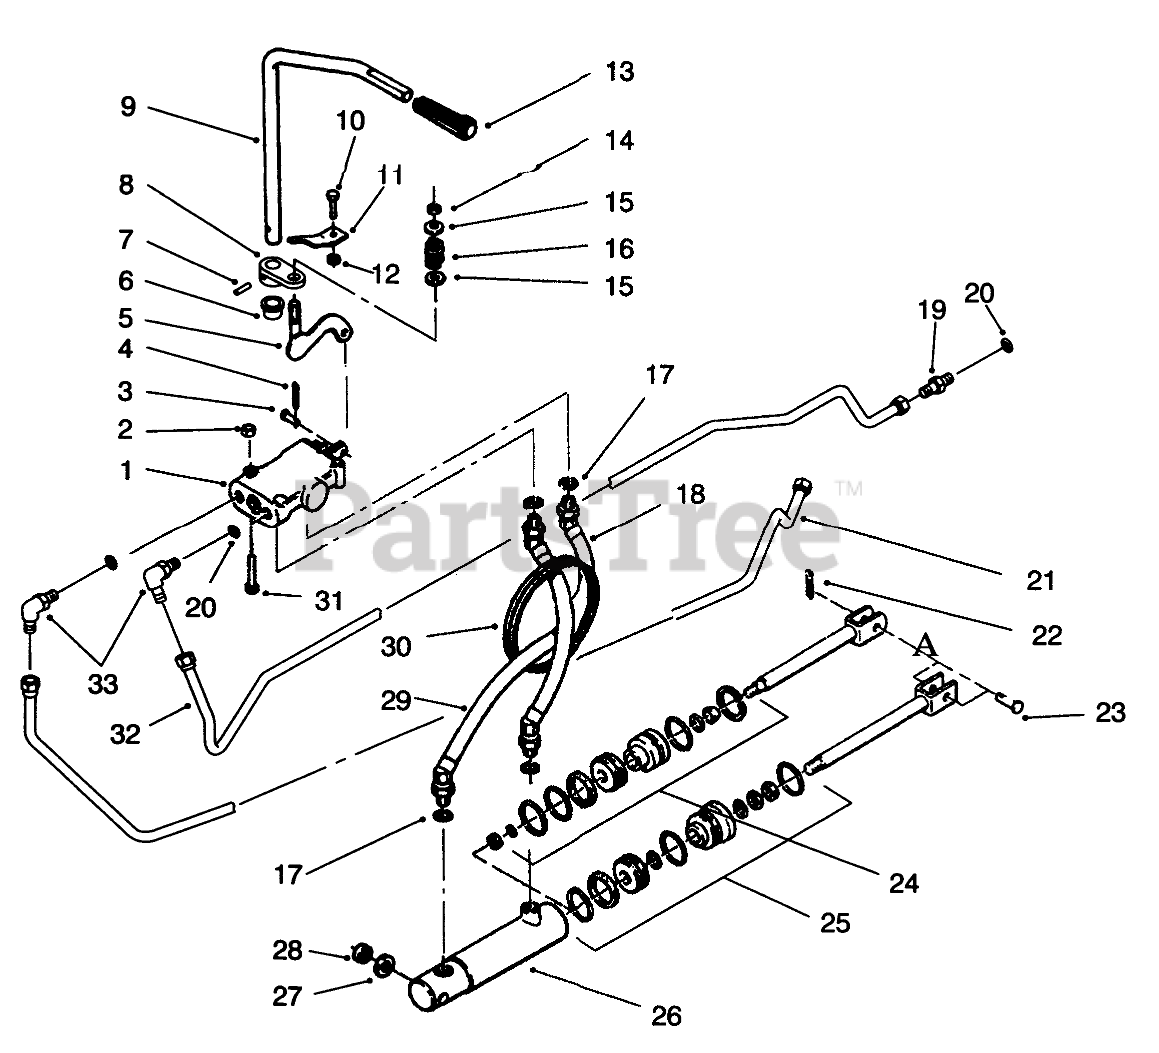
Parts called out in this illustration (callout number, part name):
1	Valve-Hydraulic (Incl. Ref. #3-4)
2	NUT-LOCK, NI
3	PIN-CLEVIS
4	PIN-COTTER
5	WLDMT-LIFT BAR
6	NYLINER BUSHING
7	SPIROL PIN 7/32X7/8
8	ARM-CONTROL
9	ROD-LIFT CONTROL
10	SCREW-HH
11	BRACKET-CONTROL R B
12	NUT-LOCK, NI
13	KNOB-HYDRAULIC LIFT
14	NUT-LOCK, NI
15	WASHER-PLAIN
16	SPRING
17	O RING
18	Hose ASM-Hydraulic
19	Fitting-Straight Adapter (Incl. Ref. #20)
20	0-Ring
21	TUBE-HYD PRESSURE
22	PIN-COTTER
23	Pin-Clevis
24	S/A O-RING&GASKET AS
25	S/A 108872 HYD CYL
26	Cylinder-Hydraulic (Incl. Ref. #24-25)
27	Washer
28	SPACER-OUTER
29	Hose ASM-Hydraulic
30	GROMMET
31	SCREW-HH
32	TUBE-HYDRAULIC
33	Fitting-90deg. (Incl. Ref. #20)
